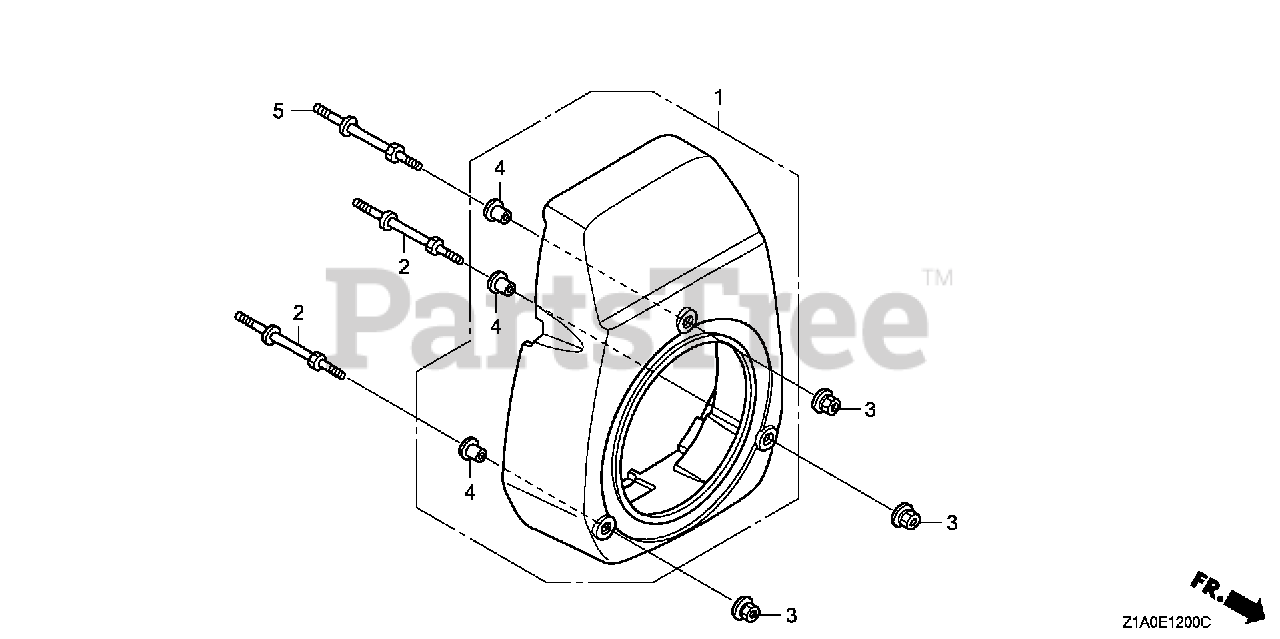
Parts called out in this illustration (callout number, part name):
1	COVER, FAN *NH1* (BLACK)
1	COVER, FAN *R280* (POWER RED)
2	BOLT, STUD
3	NUT, FLANGE (6MM)
4	COLLAR, FAN COVER (Honda Code 5580527). (N/A: SEE ASSEMBLY)
5	BOLT, STUD
